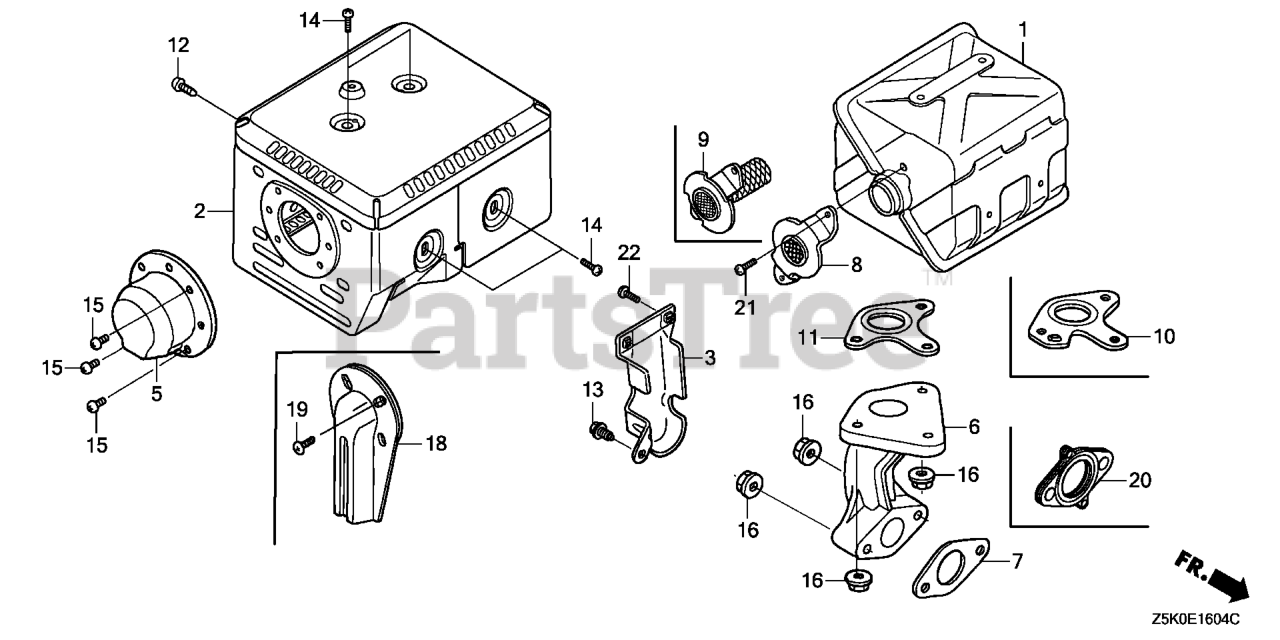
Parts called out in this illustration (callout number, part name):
1	MUFFLER
2	PROTECTOR, MUFFLER
3	PROTECTOR, EX. PIPE
5	CAP, MUFFLER
7	GASKET, EX. PIPE
9	ARRESTER, SPARK
10	GASKET, MUFFLER (ARRESTER)
10	GASKET, MUFFLER (ARRESTER)(THAI LEAKLESS)
12	SCREW, TAPPING (6X10)
13	BOLT, FLANGE (6X12) (CT200)
14	SCREW, TAPPING (5X8)
15	SCREW, TAPPING (4X6) (TO INSTALL OPTIONAL SPARK ARRESTER)
16	NUT, FLANGE (8MM)
21	SCREW, TAPPING (5X8)
22	SCREW, TAPPING (5X8)
